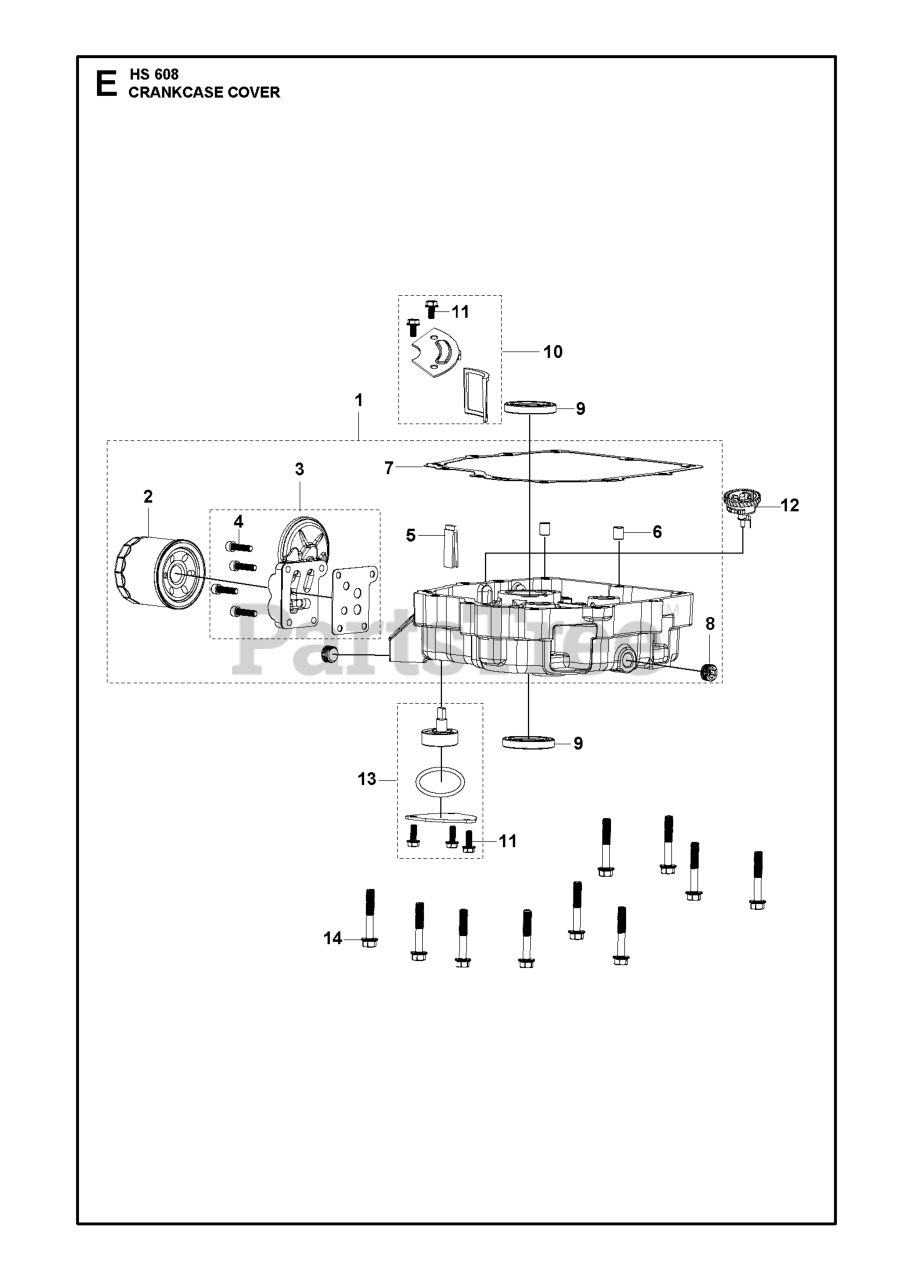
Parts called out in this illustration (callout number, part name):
1	CRANKCASE KIT CRANKCASE COVER
2	FILTER OIL FILTER (ENG.452)
3	SEAT BRACKET OIL FILTER SEAT B
4	Husqvarna TBD
5	BLOCK OIL RETURN BLOCK
6	PIN LOCATION PIN
7	GASKET CRANKCASE COVER GASKET
8	OIL PLUG OIL PLUG
9	SEAL OIL SEAL
10	STRAINER OIL STRAINER
12	GEAR GOVERNOR GEAR
13	OIL PUMP ASSY
14	BOLT T320: M8 L=50
